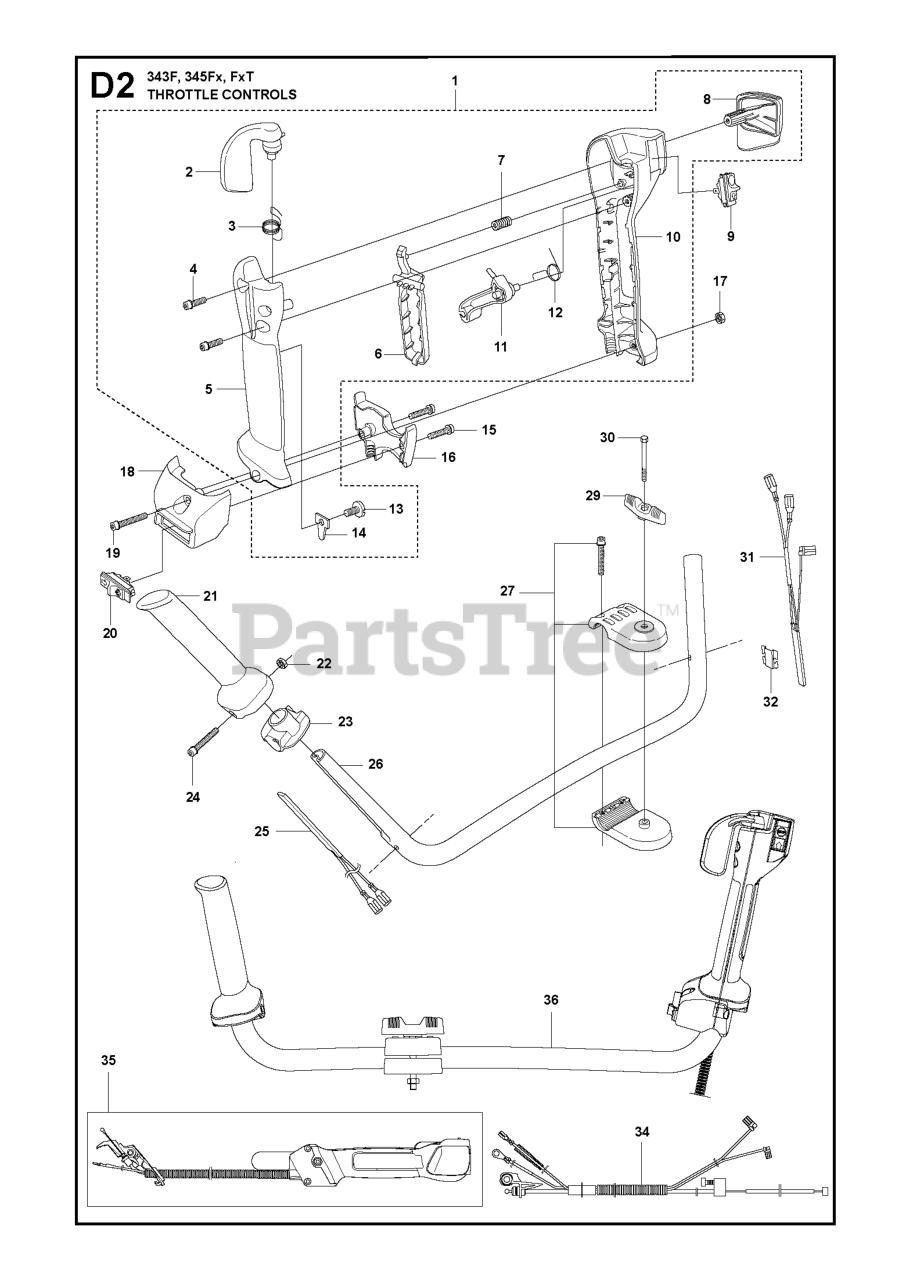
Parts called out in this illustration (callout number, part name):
1	THROTTLE HANDLE
2	THROTTLE TRIGGER
3	RP SPRING
5	HANDLE
6	THROTTLE LOCK
9	STOP BUTTON
10	HANDLE
15	SCREW
16	HOLDER
17	NUT M6M M5
18	HOLDER
19	SCREW
20	SWITCH (G)
22	NUT M6M M5
25	HEATING ELEMENT
26	%HANDLE
26	RP HANDLE
27	HANDLEBAR BRACKET KIT
30	%SCREW
31	HEATING ELEMENT
32	HOLDER
34	WIRING ASSY
35	THROTTLE HANDLE ASSY
36	HANDLEBAR
